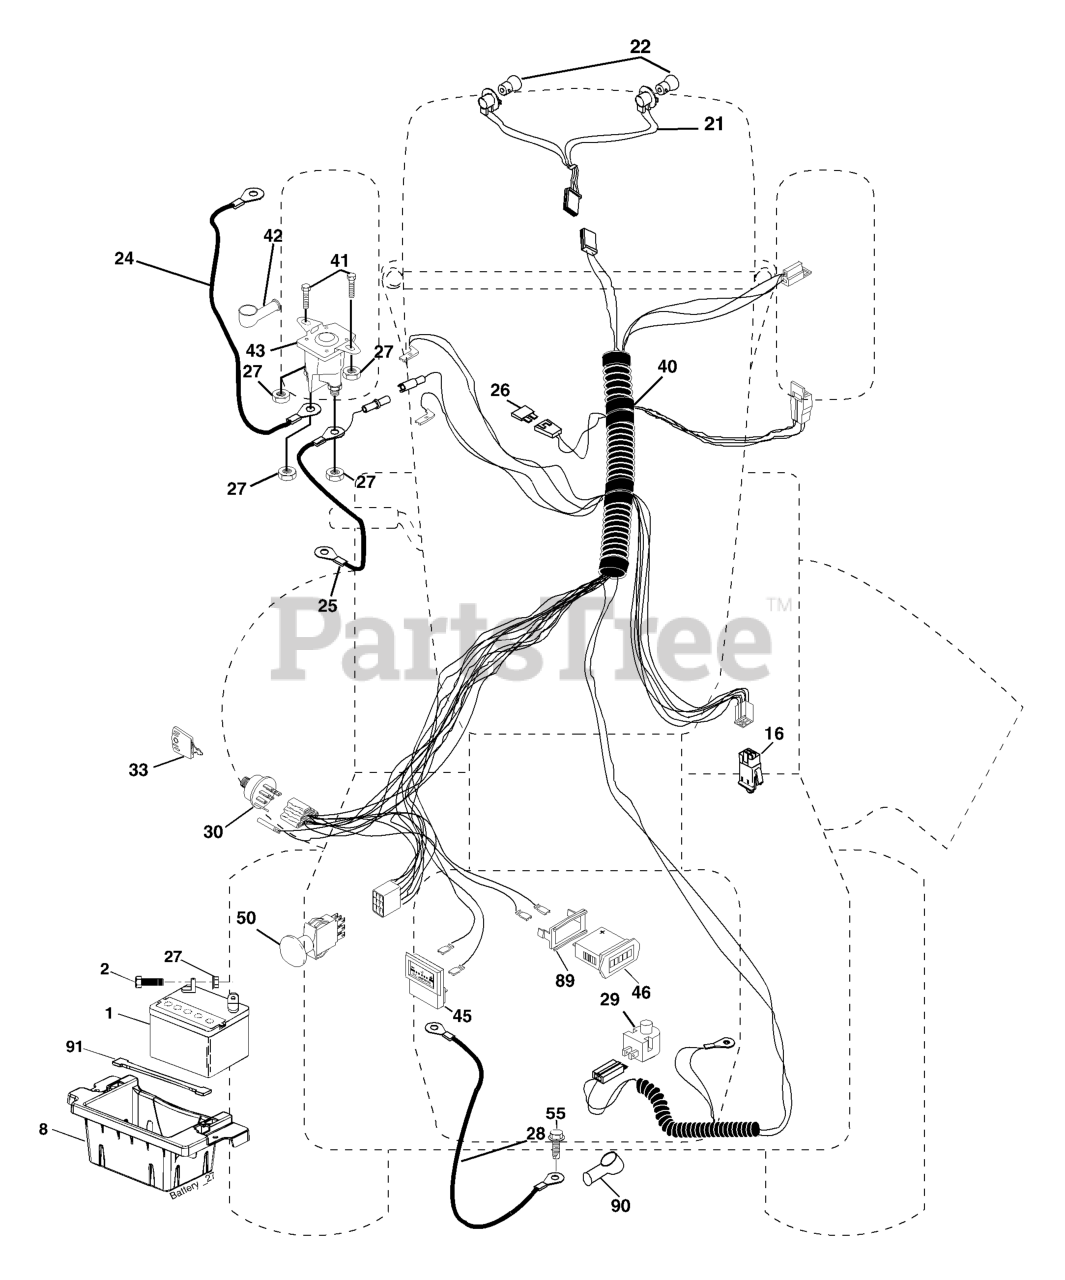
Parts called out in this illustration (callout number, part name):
1	BATTERY 12V .35 AMP
2	BOLT.HEX.1/4.X.3/4.DICHROMATE
8	BOX.BATTERY.MOUNT.FRONT.LT
10	BOLT 1/4-20 X 7.5
11	BATTERY HOLDDOWN FRONT MOUNT
12	NUT, PUSH NYLON 1/4" BATTERY
16	SWITCH INTERLOOK PUSH-IN
21	HARNESS ASSY LIGHT
24	BATTERY CABLE GT
25	CABLE BATTERY 6 GA 22" W/16W
26	FUSE 20AMP
27	NUT
28	CABLE GROUND 6 GA 21" 90T BLK
29	RP.SWITCH.PLUNGER.NC.GRAY
30	IGNITION SWITCH
33	KEY MLD GEN DELTA
40	HARNESS.IGNITION
41	BOLT
42	TERMINAL COVER
43	SOLENOID
46	HOUR METER
50	RP.PTO.SWITCH.8 TERMINAL.BLACK
55	Screw 5/16-18 x 1/2
89	BRACKET SNAP-IN HOURMETER
90	COVER TERMINAL
91	STRAP.BATTERY.MOUNT.FRONT(2 2)
